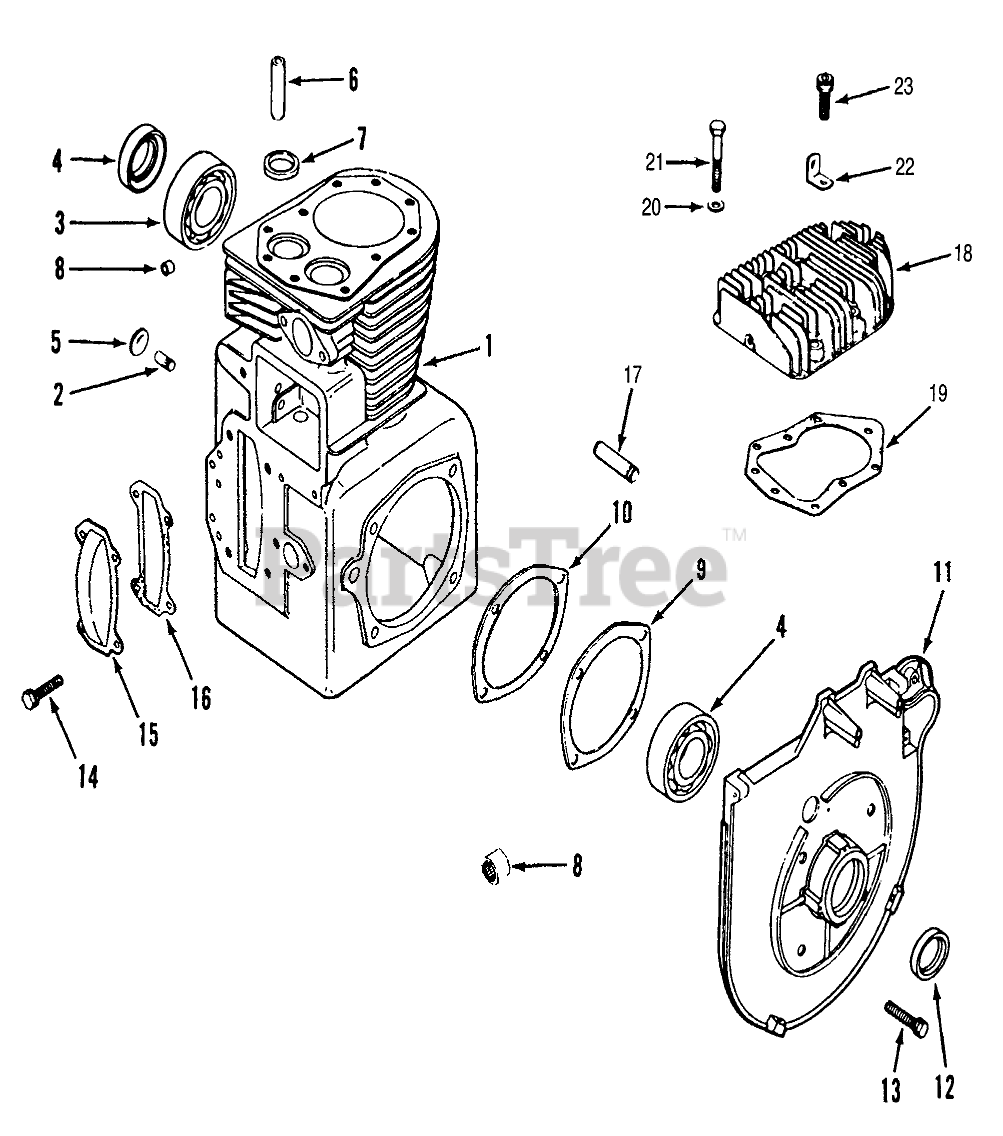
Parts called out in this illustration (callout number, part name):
1	Cylinder Block-Service With Short Block (Includes Crankshaft) 312
2	Shaft-Govemor
3	Ball Bearing
4	Seal-Rear Oil
5	Plug
6	Guide-Valve
7	Insert
8	Bearing
9	Gasket-Bearing Plate
10	Gasket-Shim
11	Bearing Plate
12	Seal-Front Oil
13	Screw
14	Screw
15	Camshaft Cover
16	Gasket
17	Shaft
18	Head-Cylinder
19	Head Gasket
20	Washer
21	Screw
22	Strap-Lifting
23	Screw-Hex Soc Hd
